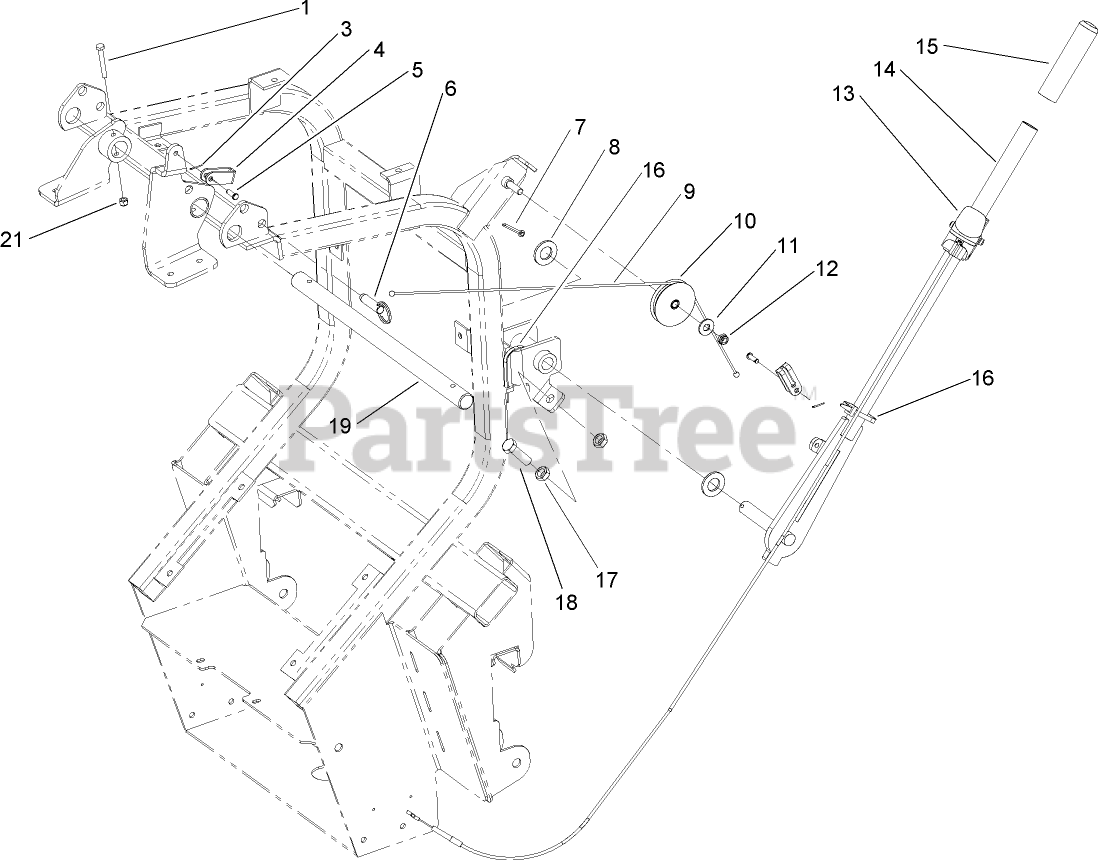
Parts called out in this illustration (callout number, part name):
1	SCREW-HH
3	PIN-COTTER
4	CLEVIS-SHORT
5	PIN-CLEVIS
6	PIN-RELEASE, QUICK
7	PIN-COTTER
8	WASHER-FLAT
9	DOOR-CABLE
10	PULLEY ASM
11	WASHER-FLAT
12	NUT-LOCK, NI
13	LATCH-CABLE, DUMP
14	DUMP ARM ASM
15	GRIP-FOAM
16	TIE-CABLE
17	NUT-JAM
18	SCREW-HH
19	SHAFT-HINGE
21	NUT-LOCK, NI
